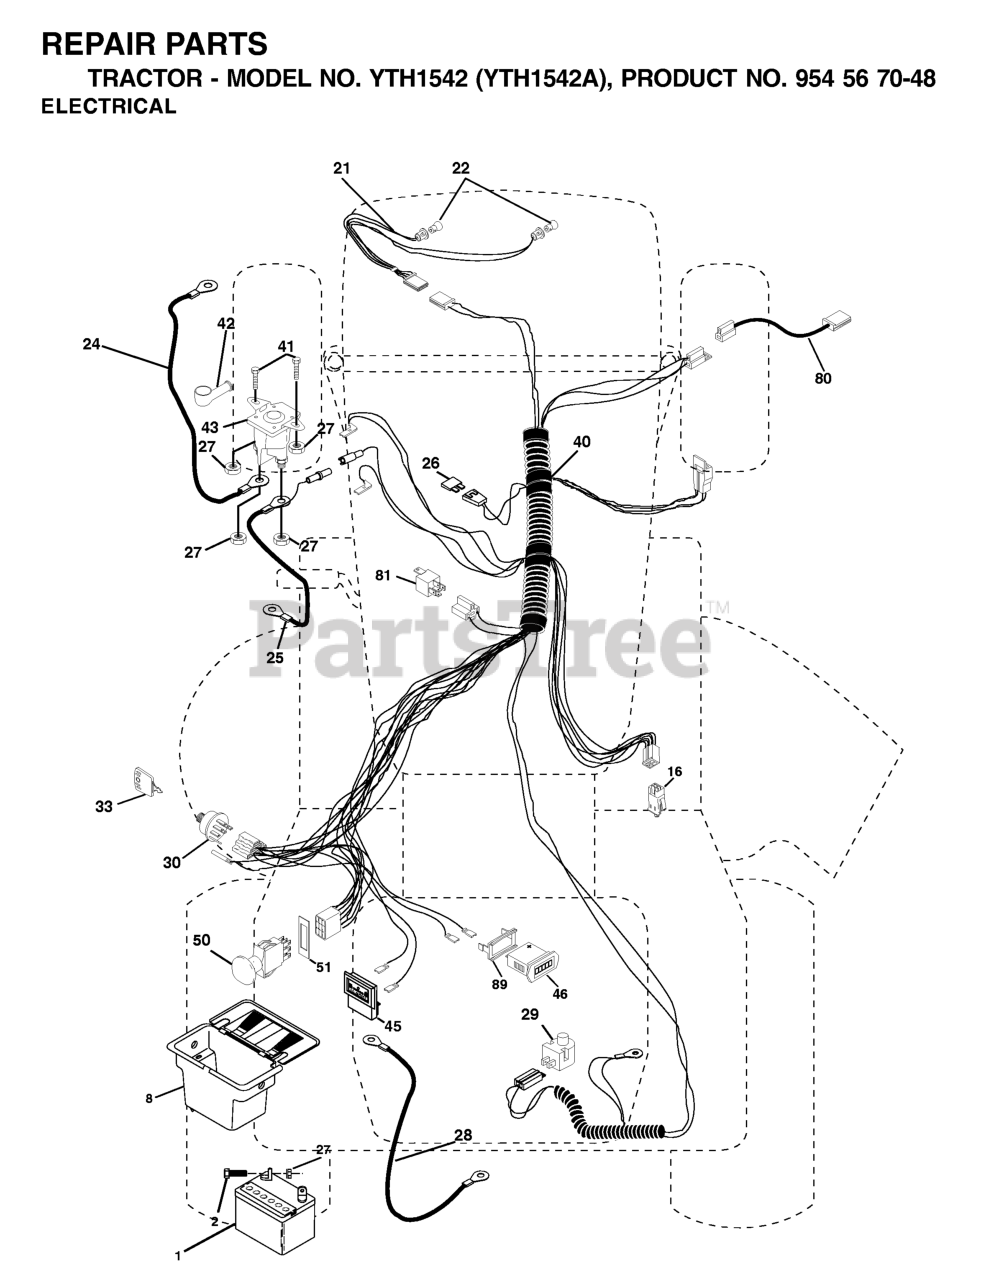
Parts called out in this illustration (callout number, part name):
1	BATTERY 12 VOLT 25 AMP
2	BOLT.HEX.1/4.X.3/4.DICHROMATE
8	CASE BATTERY MECH HINGE
16	SWITCH INTERLOCK
24	BATTERY CABLE GT
25	CABLE BATTERY
26	FUSE 20AMP
27	NUT
28	CABLE T
29	PLUNGER SWITCH (COLOR:OLIVE)
30	IGNITION SWITCH
33	KEY MLD GEN DELTA
40	HARNESS IGN.
41	BOLT
42	TERMINAL COVER
43	REPL BY 532 1461-54
46	HOUR METER
50	RP.PTO.SWITCH.8 TERMINAL.BLACK
51	FRAME RETAINING RING
80	HARNESS, CLUTCH
81	RELAY.ASSY.T
89	BRACKET SNAP-IN HOURMETER
